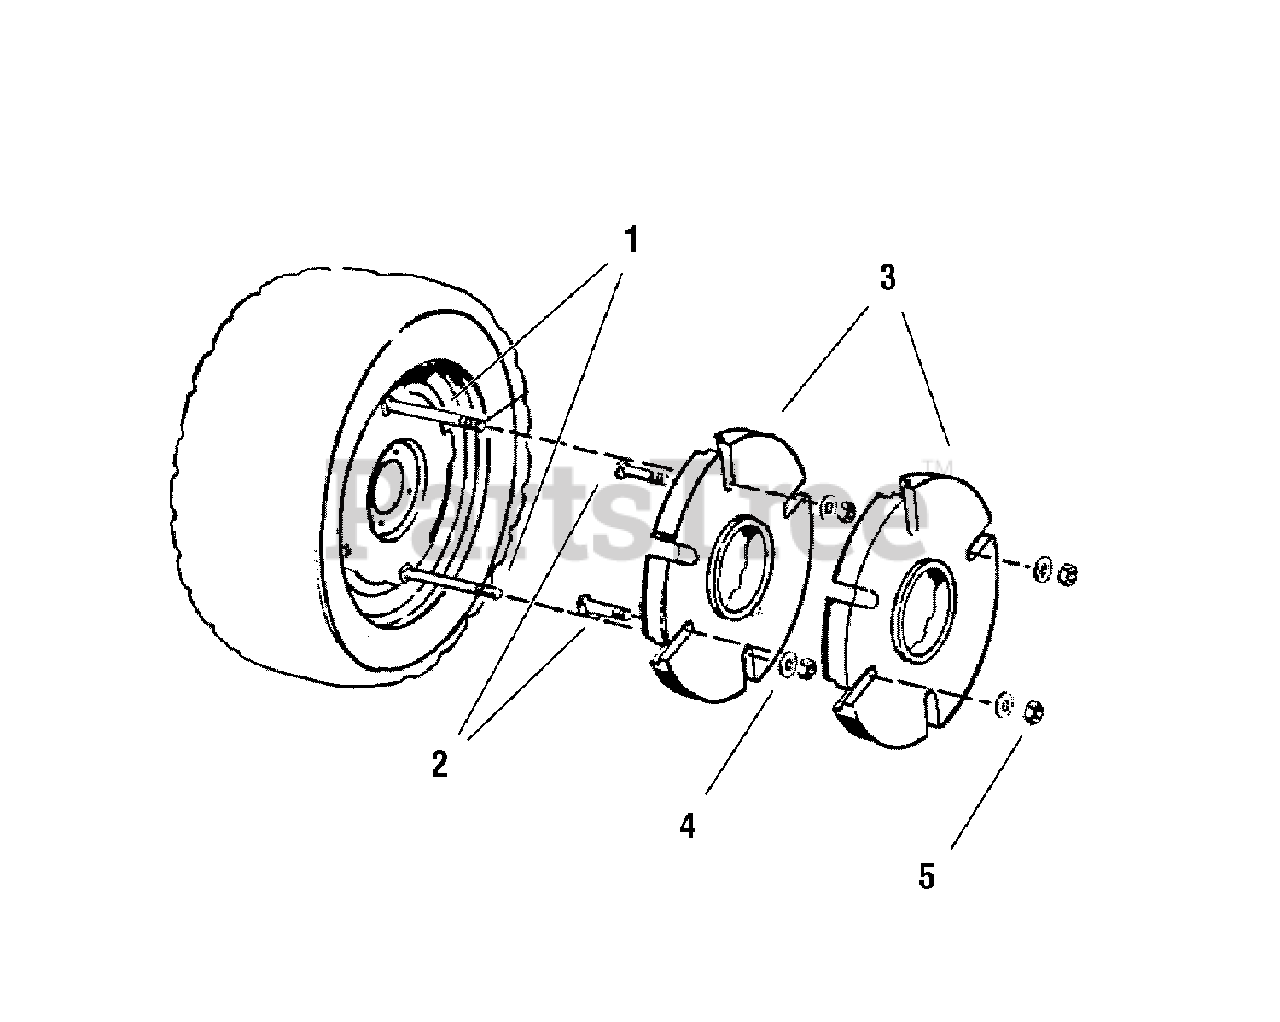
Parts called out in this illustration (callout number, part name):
1	Long Bolts
2	Short Bolts
3	Wheel Weights
